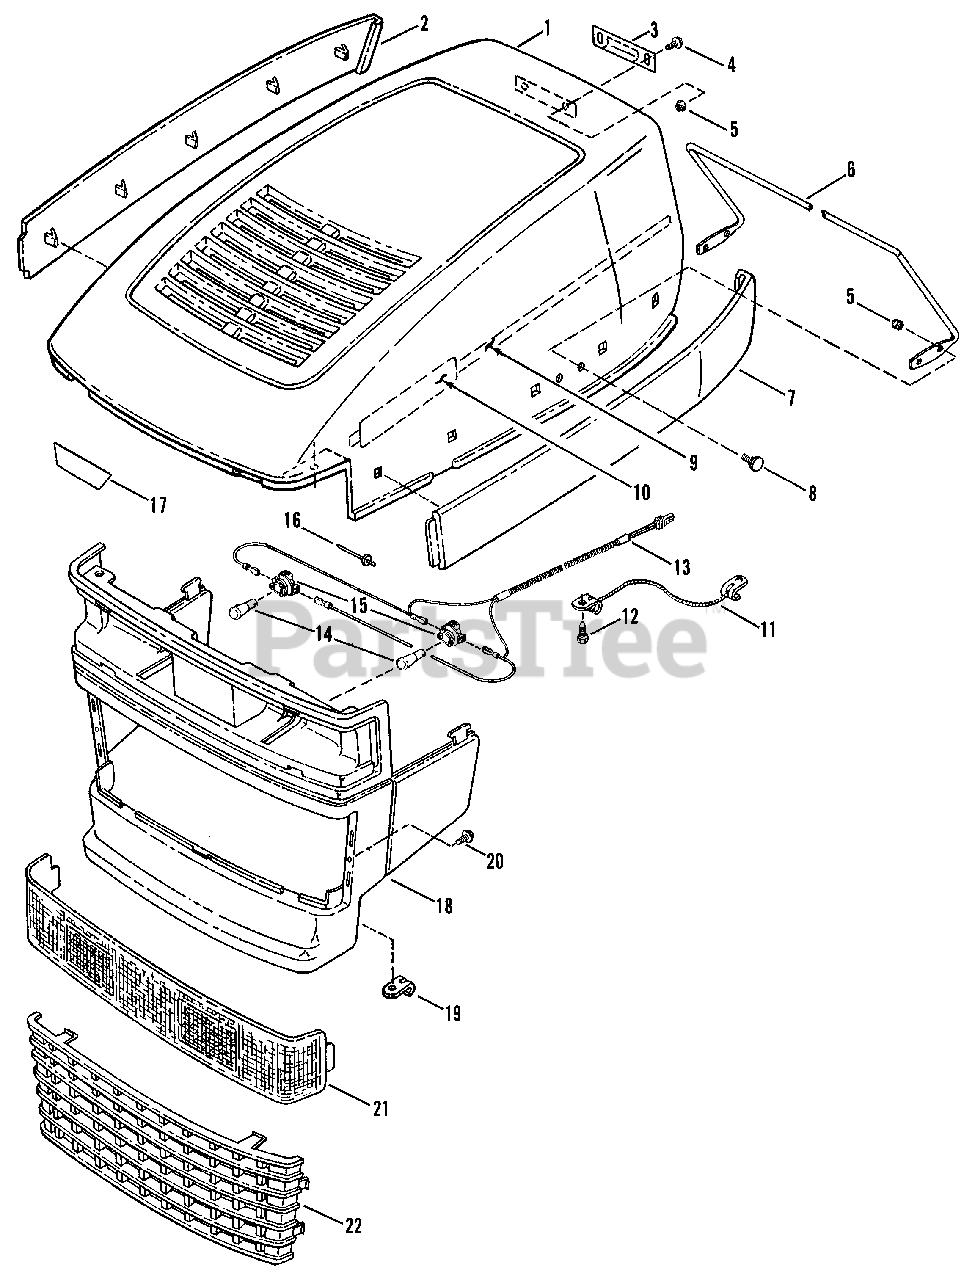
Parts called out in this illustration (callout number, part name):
1	HOOD, Replacement
2	PANEL, Hood, Right Side (Silver)
3	LATCH, Spring
4	SCREW, 1/4-20 x 5/8" Truss Head
5	NUT, 1/4-20 Hex Nyloc
6	ROD, Hood Latch
7	PANEL, Hood, Left Side (Silver)
8	BOLT, 1/4-20 x 5/8" Flat Head Carriage
9	DECAL, Hood, Left Side
10	LOGO - BLACKHAWK
11	LANYARD, Hood
12	SCREW, M4.8 x 1.59 x 16.00MM Special
13	HARNESS, Headlight Wiring
14	BULB, Headlights
15	SOCKET, Headlight Bulb
16	RIVET, 1/8" Pop
17	DECAL, Lens (Blackhawk)
18	GRILLE, Hood
19	CLIP, "J"
20	SCREW, #10-16 x 1/2" Hex Washer Head, Self-Tapping
21	LENS, Blackhawk
22	INSERT, Grille
